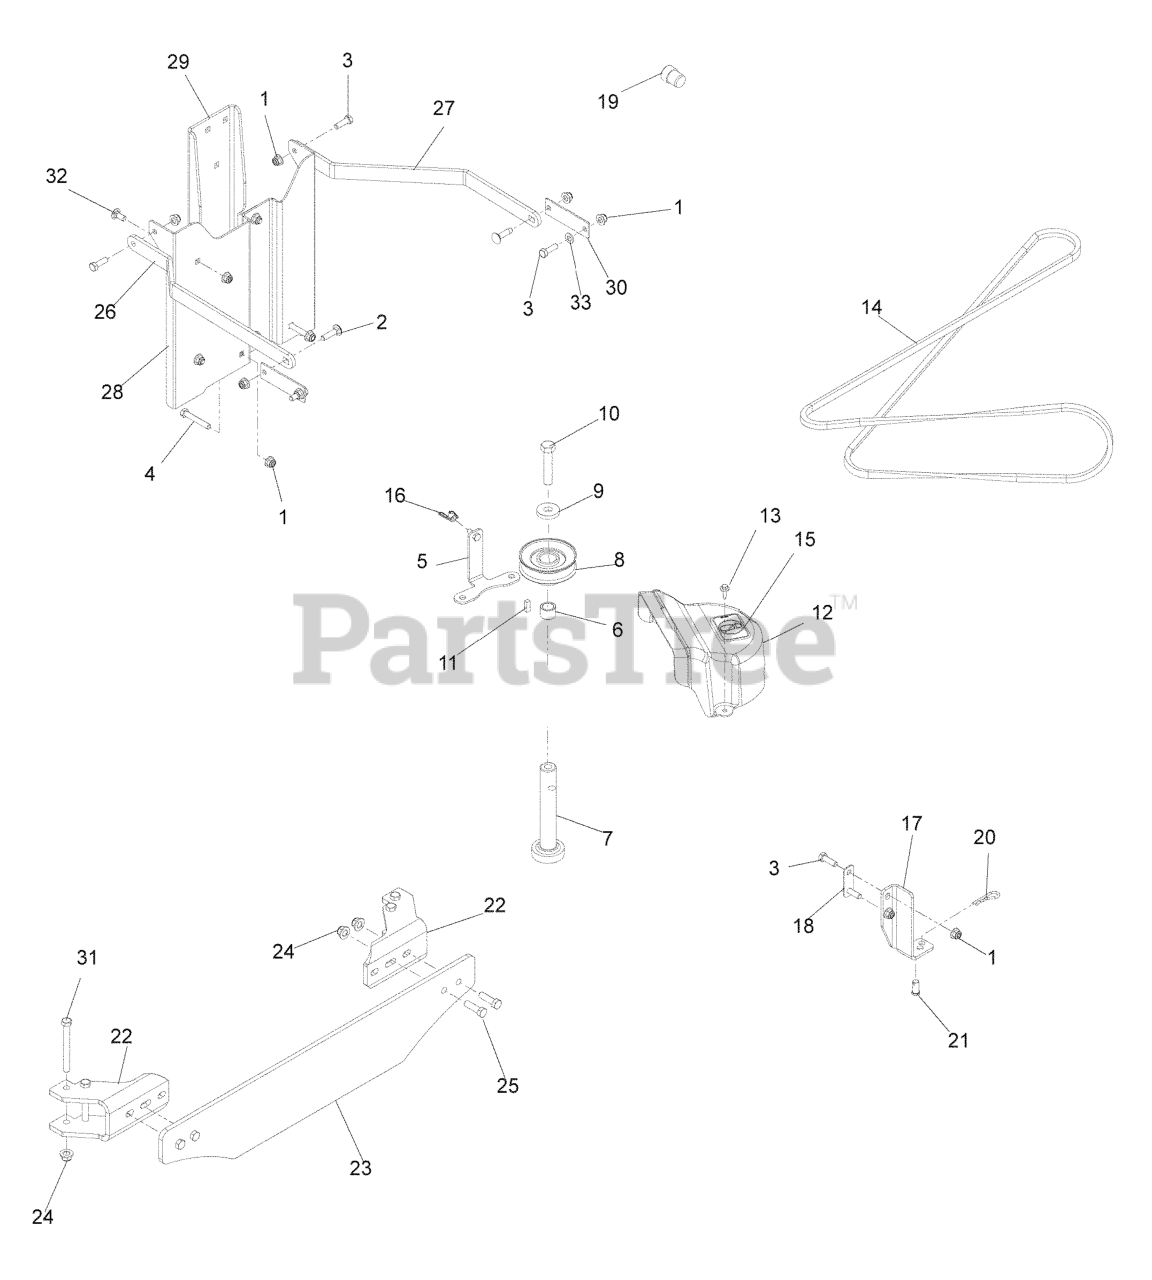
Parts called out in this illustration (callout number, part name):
1	5/16-18 NYLOC FLANGE NUT
2	BOLT, CARRIAGE 5/16X1-1/4
3	HCS 5/16C X 1
4	HCS 5/16-18X2
5	BELT SHIELD STANDOFF - 44
6	SPACER, DRIVE PULLEY - .680"
8	PULLEY, SPDZTR 44
9	WASHER .525 X 1.375 X .25
10	BOLT, 1/2-20 X 2-1/2
11	OUTER SHAFT KEY
12	SHIELD, BELT - 44 SPDZTR
13	SCREW, TAP & DR #12-14 X 3/4
14	BELT A-83 KEVLAR
15	DECAL, NO STEP
16	WING NUT 1/4
17	BRACKET, HOLD DOWN
18	PLATE, BACK UP
19	SPACER PLUG, BAGGER
20	RETAINER SPRING
21	CLEVIS PIN
22	BRACKET WEIGHT BLK
23	WEIGHT PLATE, BLACK
24	NUT 3/8-16 HEX FLG NYLOC ZD
25	HCS 3/8C X 1 1/4 GR5
26	STRAP, SUPPORT, RT BLK
27	STRAP, SUPPORT, LT BLK
28	MOUNT, 2 BIN COLLECT, BLK
29	BRACKET, COLLECTION BLK
30	REINFORCEMENT PLATE BLK
31	HCS 3/8-16 x 3½
32	BOLT 5/16C X 3/4" CARRIAGE
33	FLAT WASHER 5/16 SAE
